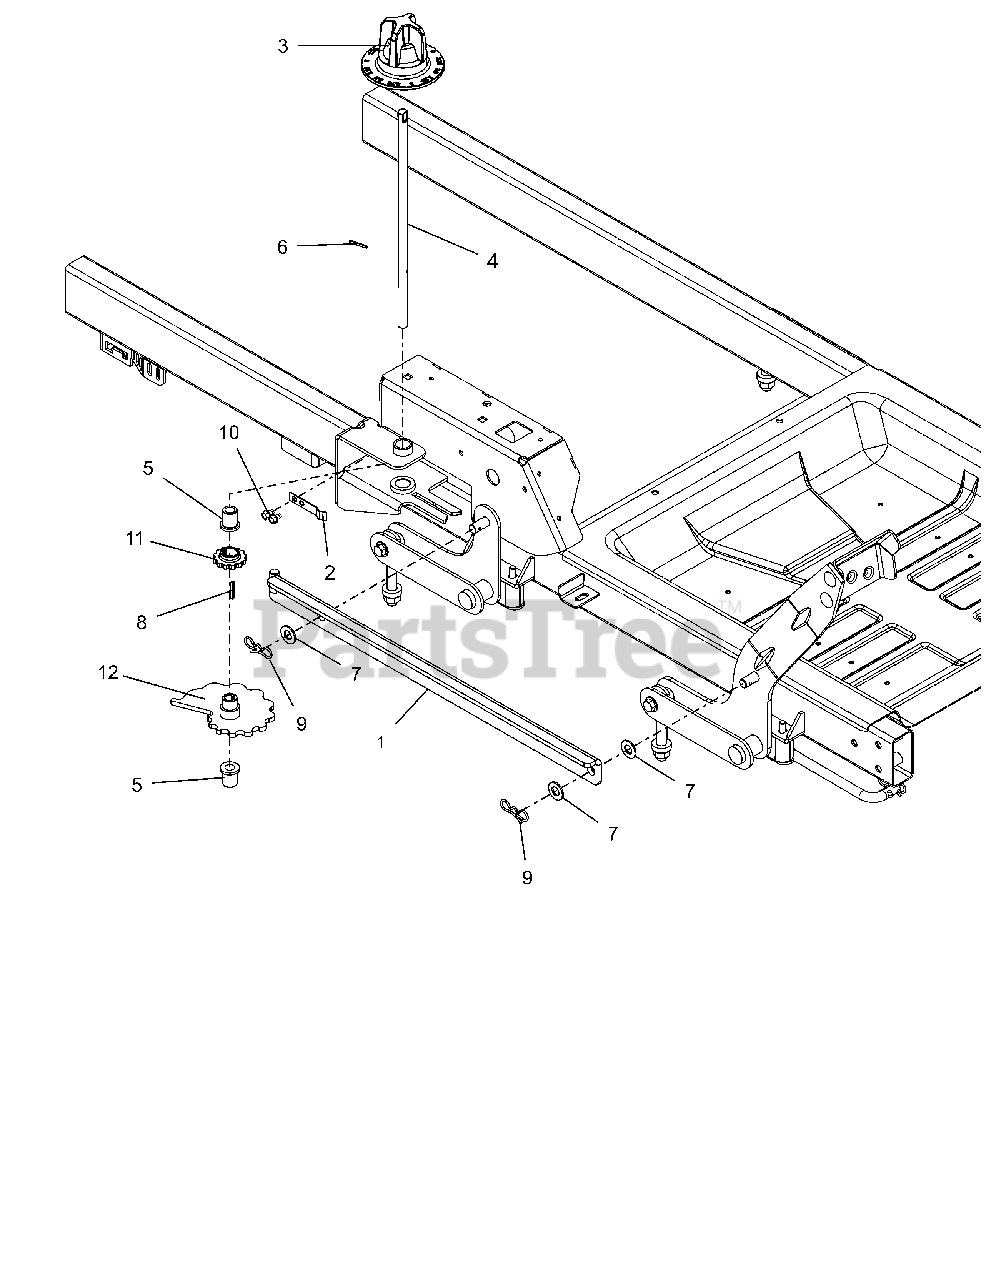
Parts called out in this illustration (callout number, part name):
1	WLDMT, HOC LINK
2	ARM, HOC DETENT
3	KNOB, HOC DIAL
4	SHAFT, HOC CAM
5	BSHG-FLG, .503X.750X.875X1.00
6	PIN-ROLL .125X1.00
7	WSHR-FL-NYL .518X1.000X.080
8	KEY, 1/8 X 1/8 X 1.0
9	PIN,BOW TIE LOCKING .091X1.875
10	SCR,TAP .25-20X.375 HWH TR ZCC
11	GEAR, HOC INDEX
12	WLDMT, HOC CAM
